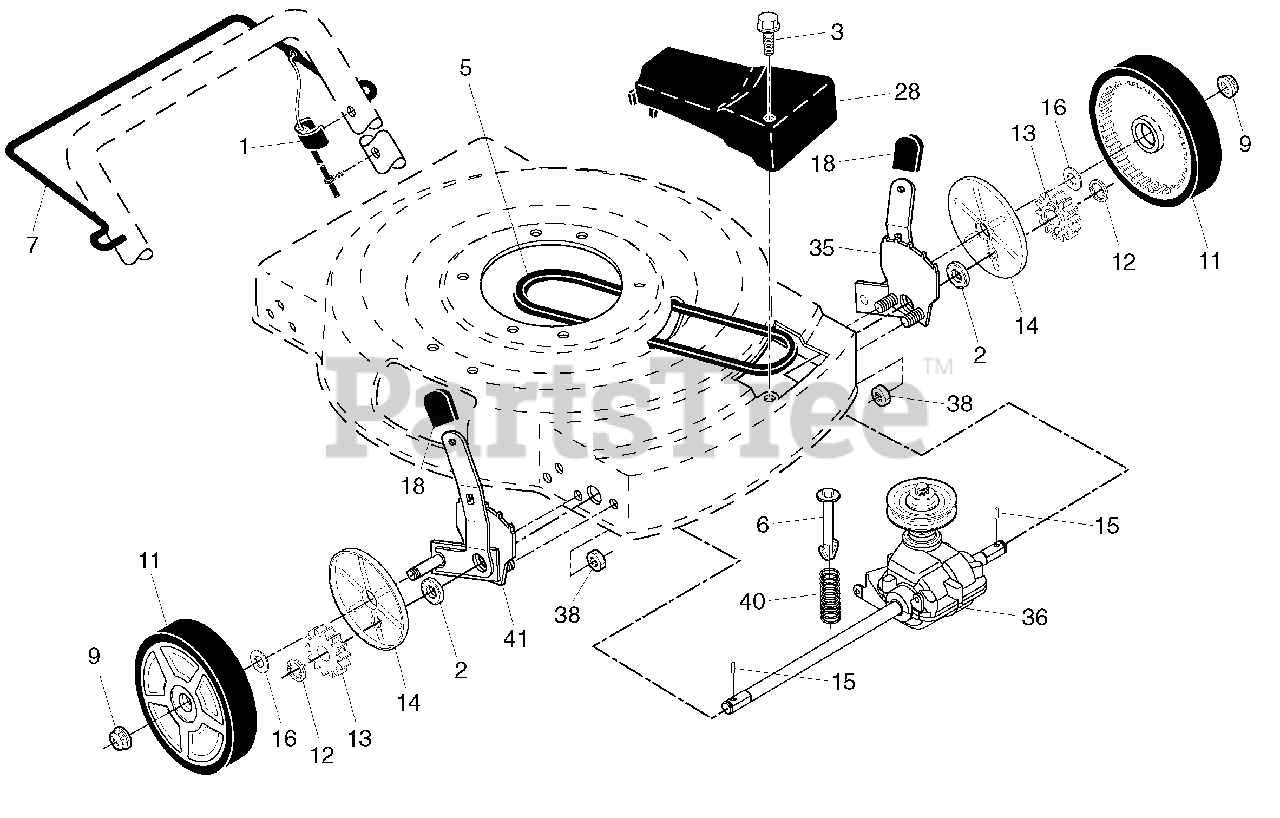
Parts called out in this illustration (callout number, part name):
1	Drive Control Cable Assembly
2	Bearing, Wheel Adjuster
3	Pan Head Tapping Screw #10-24 x 2-3/4
6	Spring Retainer
7	Control Bar, Drive
9	Locknut, Hex
11	Wheel & Tire Assembly
12	E-Ring
13	Pinion
14	Dust Cover
15	Pawl, Drive
16	Washer
18	Selector Knob
28	Drive Cover
35	Kit, Wheel Adjuster, LH
36	Gear Case Assembly, Complete
38	Locknut, Hex 1/4-20
40	Spring
41	Kit, Wheel Adjuster, RH
